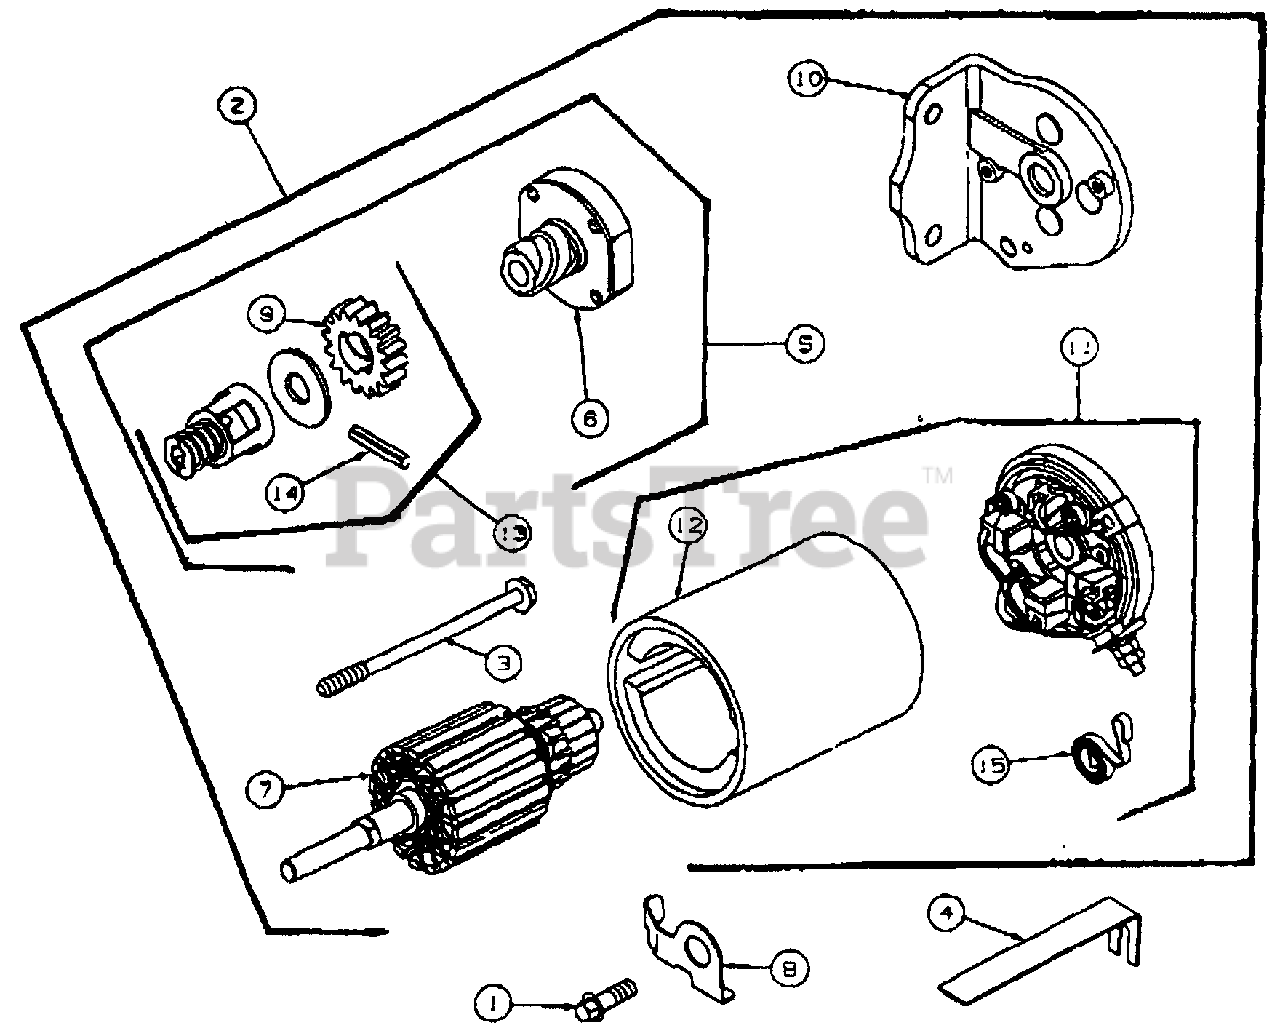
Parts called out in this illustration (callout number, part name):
1	Screw, Hex
2	Starter Assy., Motor
3	Screw, Hex
4	Strap, Starter
5	Starter, Drive Group
6	Clutch Assy
7	Armature Assy
8	Clip, Wire
9	Gear, Starter
10	Drive End Cap Assy
11	Cap Assy, Commutator End
12	Housing Assy
13	Kit, Gear
14	Pin, Roll
15	Spring, Brush
